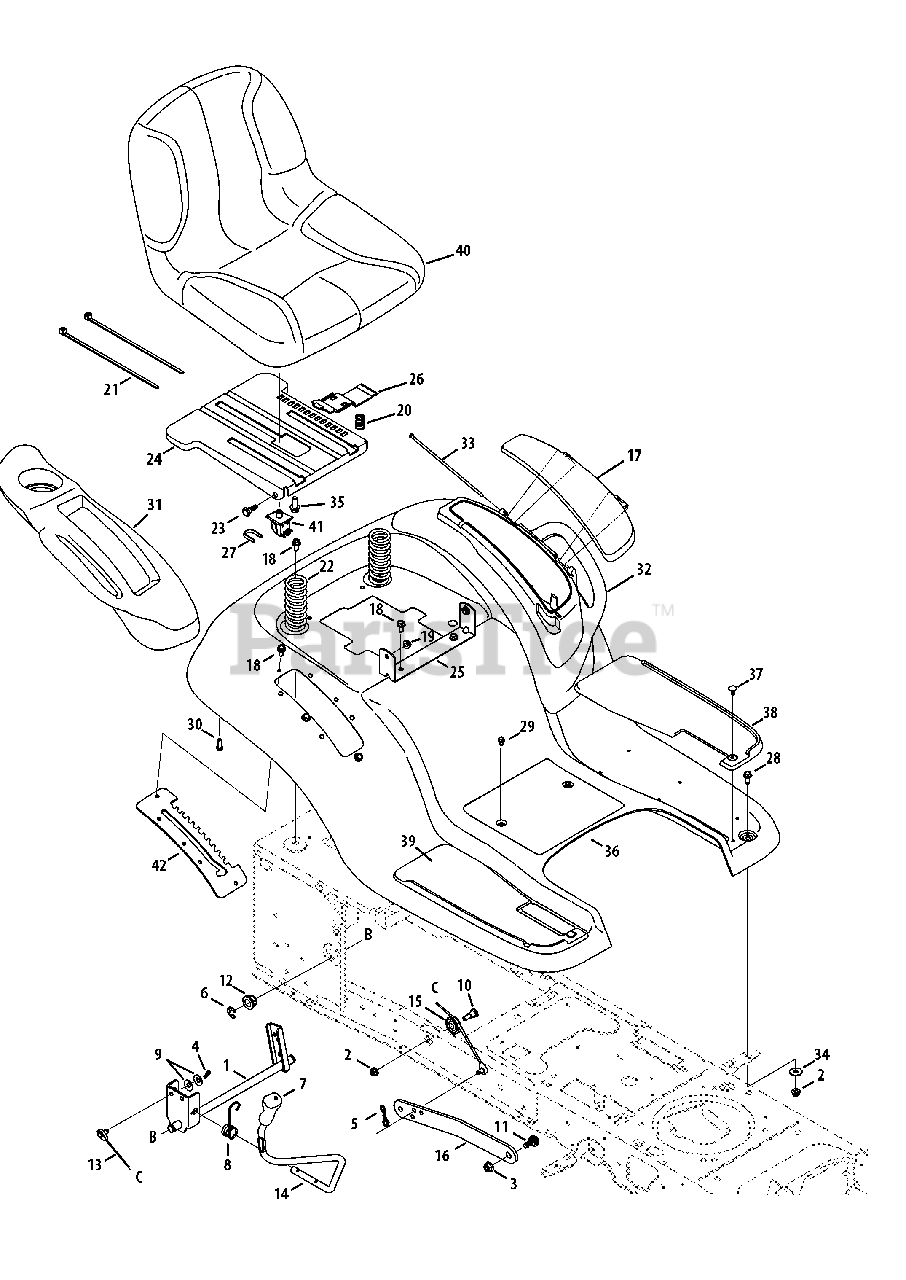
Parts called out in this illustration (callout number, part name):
1	Shaft Ass’y, Lift
2	Nut, Flange Lock, 5/16-18, Grf
3	Nut, Flange Lock, 3/8-16, Grf
4	Pin, Cotter, .072 Dia. x 1.13
5	Pin, Cotter, Bow-Tie 72
6	Ring, E Type, .625 Dia. Shaft
7	Grip, H&le, Cub, .50 ID
8	Spring, Torsion
9	Washer, Spring, .401 x .870 x .063
10	Screw, Shoulder, .437 x .470, 5/16-18
11	Bolt, Shoulder, .50, 3/8-16
12	Bearing, Hex Flange
13	Cable, Lift, 16.16
14	H&le, Lift,
15	Pulley, Roller, Cable
17	Door, Cover, Fender
18	Screw, Self-tapping, 5/16-18, .750,
19	Nut, Flange Lock, 5/16-18, Gr5, Sd Lk
20	Spring, Compr’, .68 x 1.065 x .055
21	Cable, Tie, 3/16 x .05 x 7.4
22	Spring, Comprs, 1.50 x 3.90 x .200
23	Screw, Shoulder, .437 x .268, 5/16-18
24	Bracket, Mounting, Seat
25	Bracket, Pivot, Seat
26	Lever, Seat Adjustment
27	Clip, Retaining, Switch
28	Hex Screw, 5/16-18, .75, Gr5, Std
29	Screw, Self-tapping, 1/4-20, 0.500,
30	Screw, HL, 1/4-15, 0.750,
31	Cover, Fender, RH
32	Cover, Fender, LH
34	Washer, Flat .344 x 1.00 x .063
35	Hex Flange Screw, 3/8/16, .875, Gr5
36	Fender, Cub Hydro
37	Clip, Ratchet, .250 Dia
38	Pad, Foot, LH
39	Pad, Foot, RH
40	Seat, High Back Cloth, Cub
41	Switch, Seat
42	Bracket, Lift
